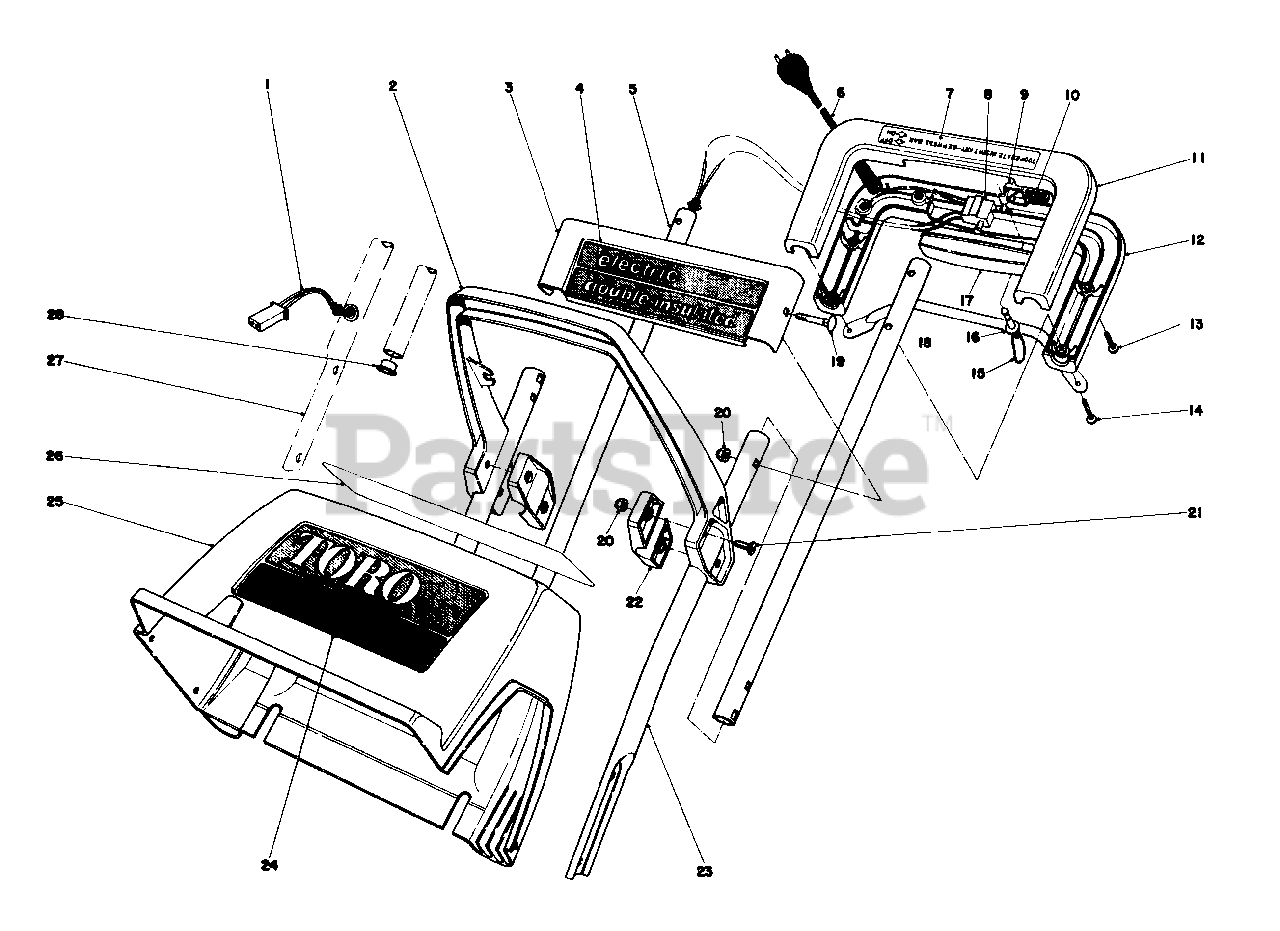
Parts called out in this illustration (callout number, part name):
1	Wire Harness
2	Middle Handle
3	Escutcheon Plate
4	Decal-Electric
5	Upper Tube
6	Cord Supply
7	Decal-Handle
9	Lockout-Switch
10	Spring Compression
11	Handle-Upper Control
12	Handle-Lower Control
13	Screw
15	Key Chain
16	Key
17	Switch Bar
18	Switch Guard
19	Carriage Bolt
21	Screw Round Head
22	Clamp-Middle Handle
23	Handle-Lower L.H.
24	Decal-Toro S-120
25	Shroud S-120
26	Decal U.L.
27	Handle Lower R.H.
28	Snap Bushing
